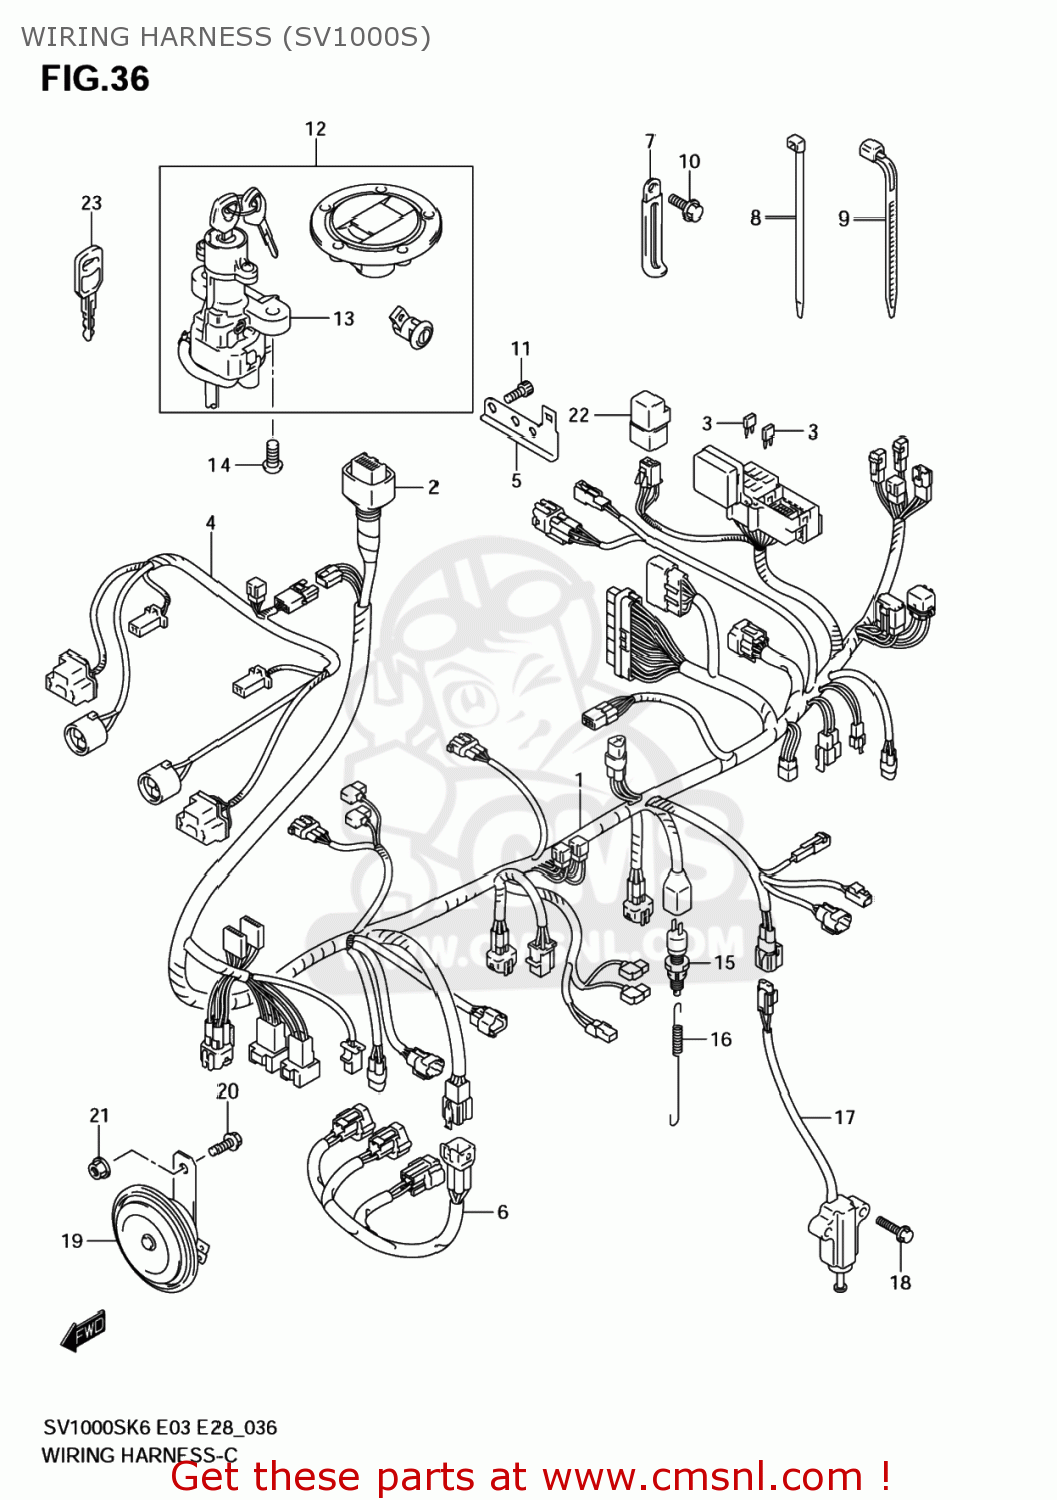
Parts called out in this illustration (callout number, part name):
1	HARNESS,WIRING NO.1
2	COVER,SPEEDOMETER COUPLER
3	FUSE(10A)
4	HARNESS,WIRING NO.2
5	HOLDER,COUPLER
6	WIRE,INJECTOR LEAD
7	CLAMP(L:45)
8	CLAMP(L:145)
9	CLAMP(L:95)
10	BOLT
11	BOLT
12	LOCK SET
13	LOCK ASSY,STEERING
14	BOLT(8X20)
15	SWITCH ASSY,STOP LAMP
16	SPRING
17	SWITCH ASSY,SIDE STAND
18	BOLT
19	HORN ASSY
20	BOLT
21	NUT
22	RELAY ASSY
23	KEY,BLANK
